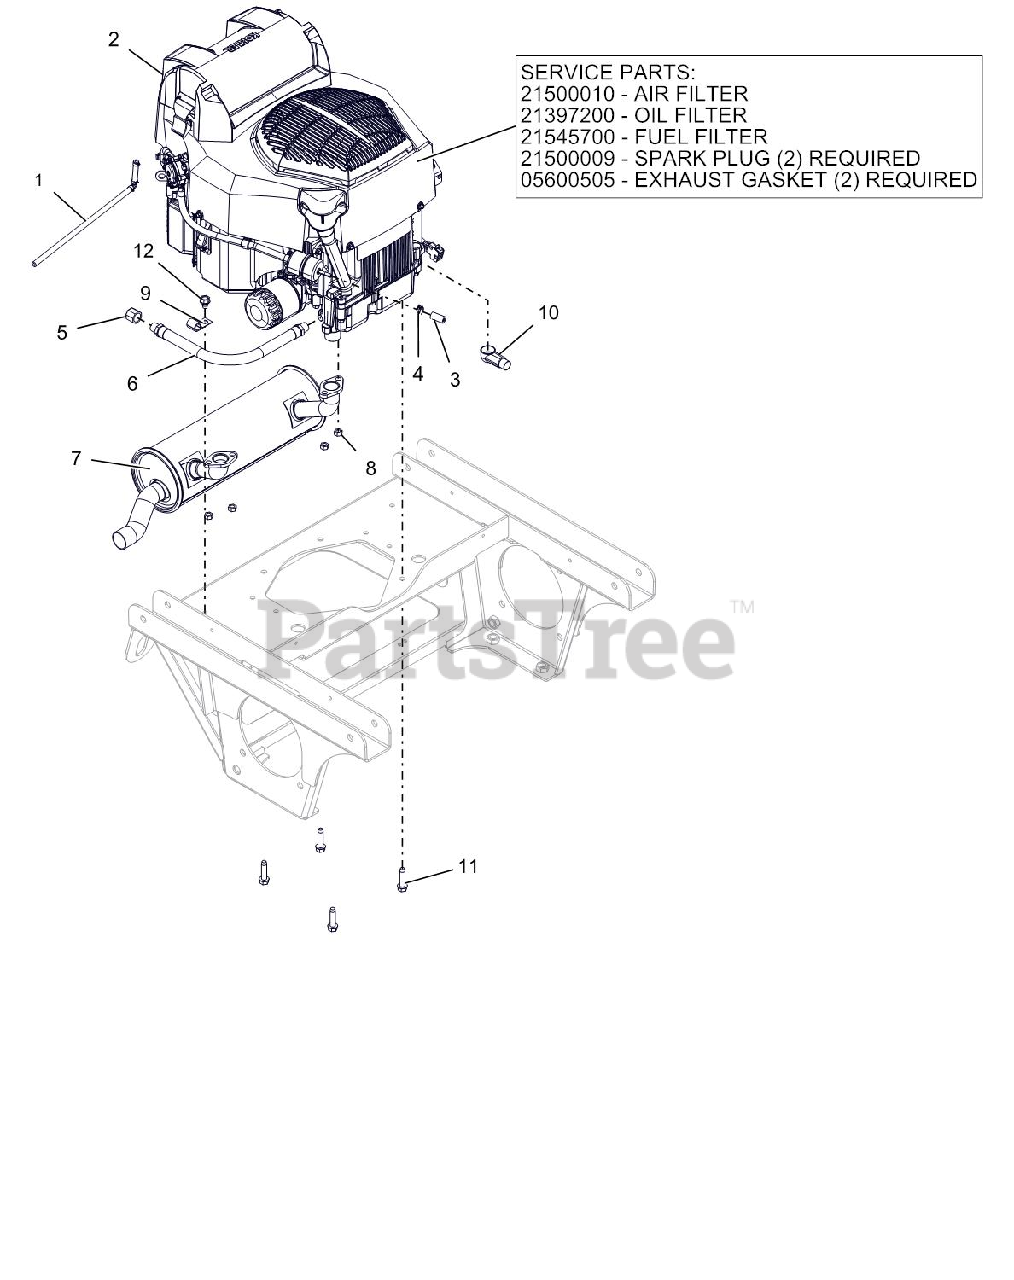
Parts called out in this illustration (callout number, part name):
1	ASM, VAPOR LINE
2	FILTER, OIL - KOH CV20
2	GASKET, MUFFLER KOHLER TWIN
2	AIR CLEANER, KOHLER CONFIDANT
2	FILTER-FUEL KOHLER COURAGE PRO
2	PLUG, SPARK KOHLER
2	ENGINE, KOHLER ZT740 CONFIDANT
3	HOSE, .25 LOW-PERM BULK GAS
4	CLAMP, FUEL LINE
5	PIPE CAP 3/8 NPT FEMALE
6	HOSE,HYD .38-14-0K M6N0-M6N0
7	MUFFLER, ZT730/ZT740
8	NUT-LK-TOP M8-1.25 YWZC
10	BOOT, .65ID POS
11	@SCR-TAP .38-16X1.50 HWH TR YZ
12	@SCR-TAP .38-16X.50 HWH TR YWZ
